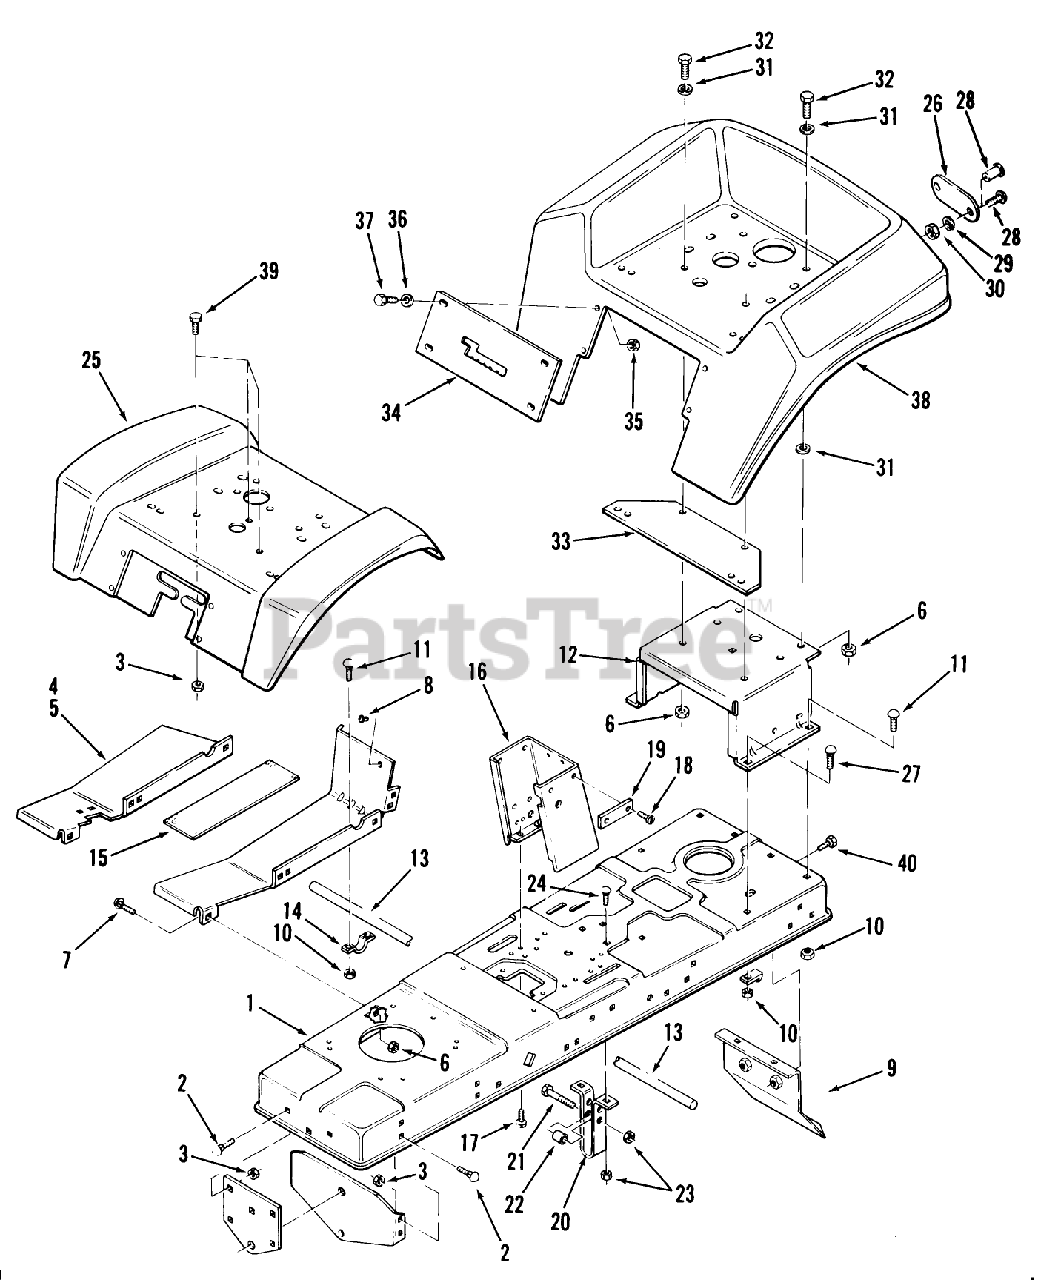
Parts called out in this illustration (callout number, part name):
2	CARRIAGE BOLT -4
7	CARRIAGE BOLT -4
8	BUMPER-RUBBER
11	CARRIAGE BOLT -4
12	SUPPORT-SEAT *R
13	SHAFT-REAR
14	CLAMP
15	PAD-FOOTREST
17	SCREW
27	CARRIAGE BOLT -4
31	WASHER
